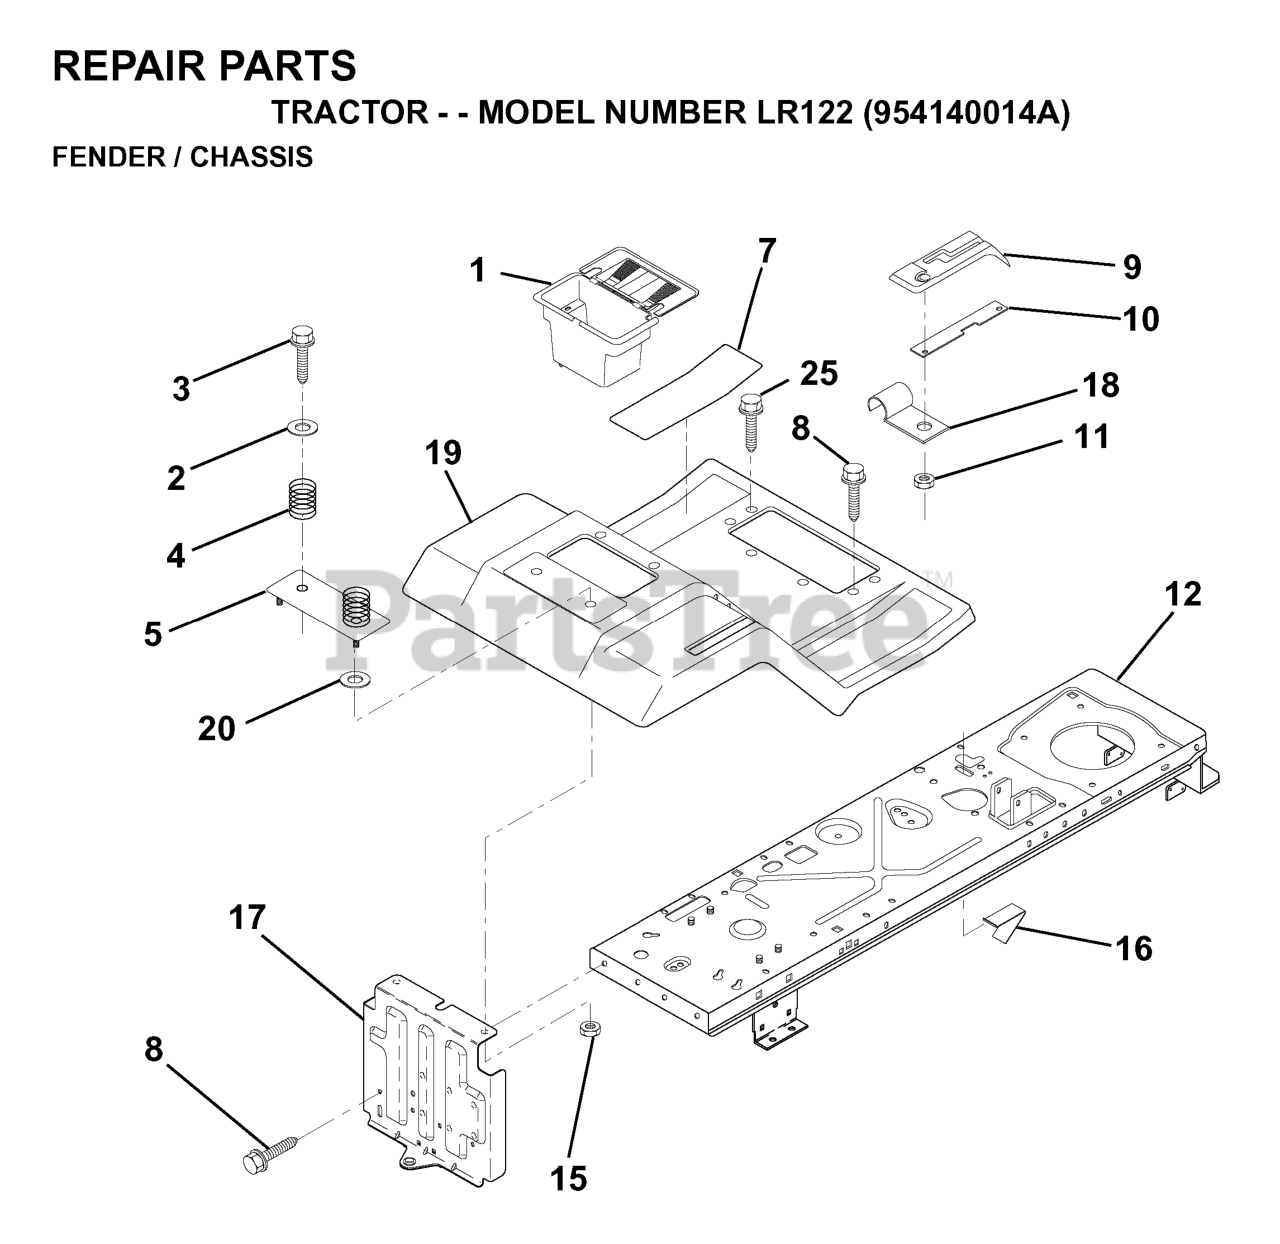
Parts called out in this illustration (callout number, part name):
1	CASE BATTERY MECH HINGE
2	WASHER
3	SCREW
4	SPRING COMPRESSION
5	PLATE ASM BATTERY
7	PAD FOOTREST
8	SCREW.THDROL.5/16-18X3/4.TTY
9	SHIFT CONSOLE
10	BAR, SHIFT LOCK
11	NUT.PUSH.3/16
15	Nut, Keps Blk Hex 1/4-20 UNC
16	SWITCH ACTUATOR
18	CLIP,INSULATOR
19	FENDER/FOOTREST
20	WASHER
25	Screw Hex Wsh Thdroll 5/16-18 x 1
